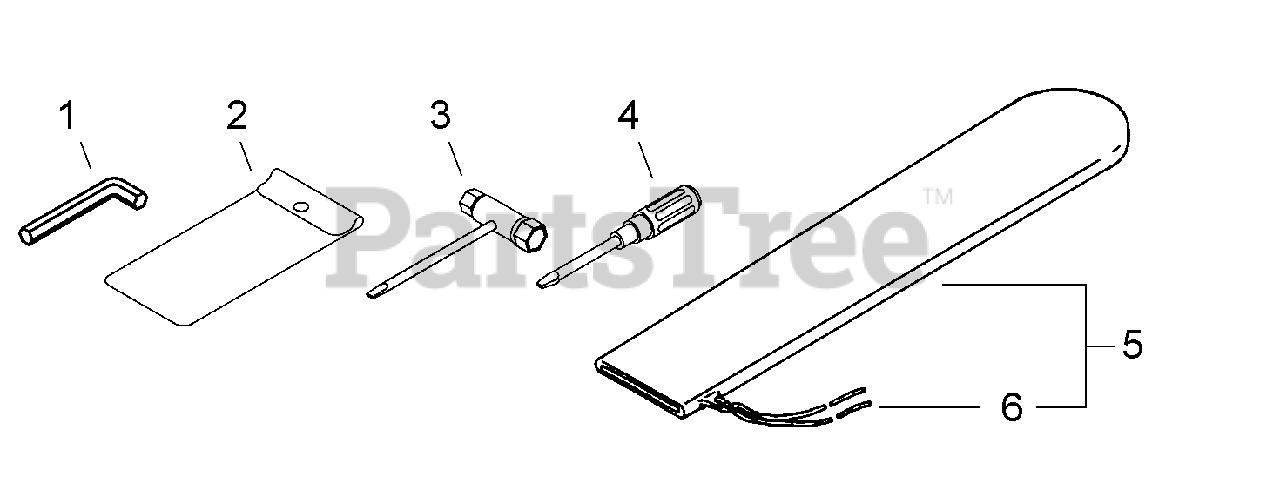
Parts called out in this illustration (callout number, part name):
1	HEX KEY - 4mm
2	BAG, TOOL
3	T-WRENCH - 13X19mm
4	SCREWDRIVER
5	COVER, CHAIN
